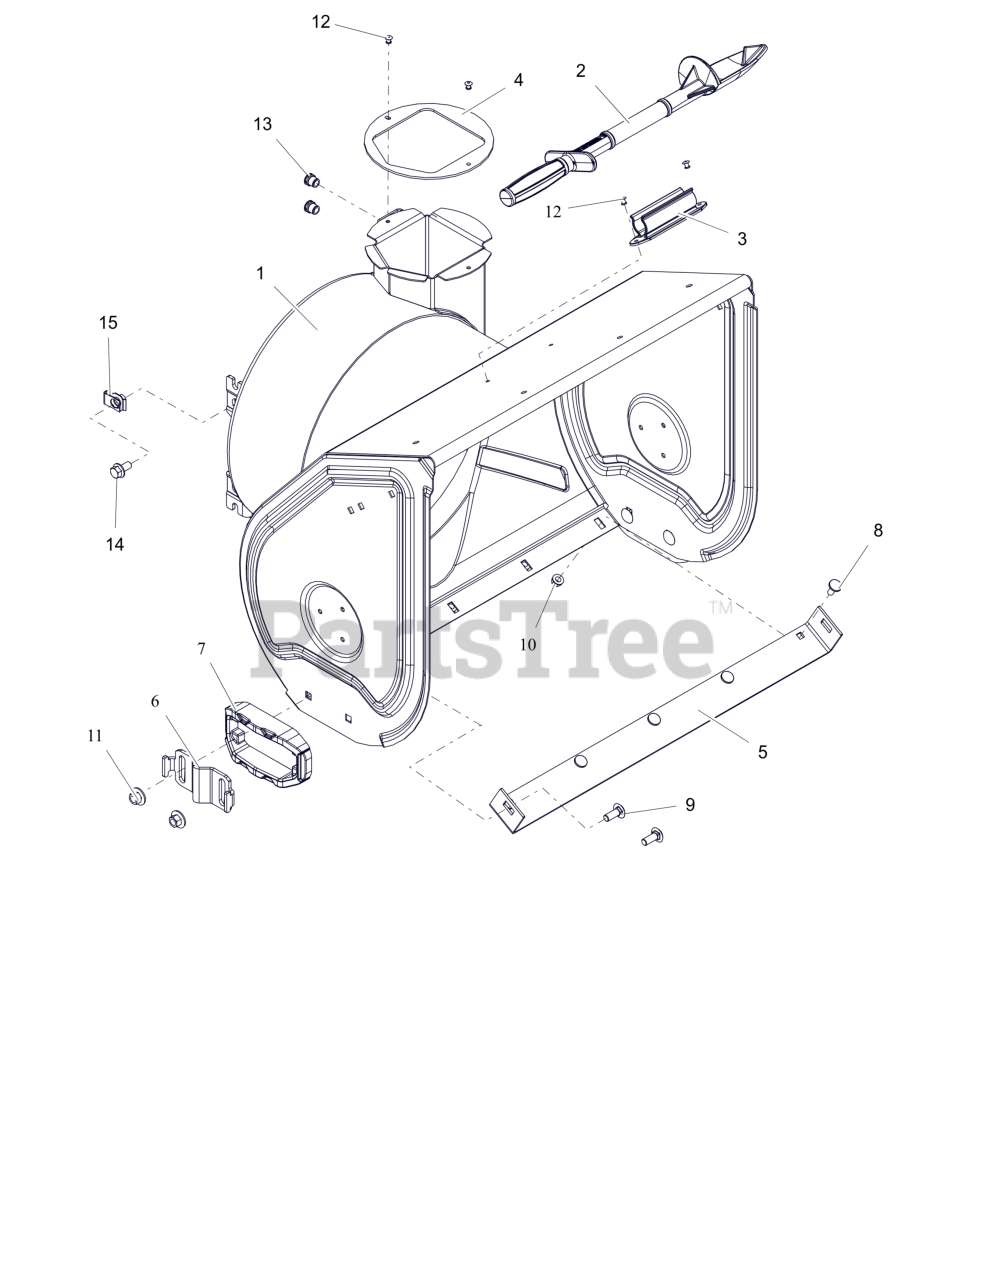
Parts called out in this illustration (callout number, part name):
1	HOUSING, BLOWER W/DECALS 24"
2	DEVICE, SNOW CLEAN OUT
3	MOUNT, SNOW CLEAN OUT
4	BAFFLE, DISCHARGE NECK
5	BLADE, SCRAPER-24"
6	SHOE, SKID - INSERT (BLACK)
7	SHOE, SKID - WEAR
8	BOLT, MODIFIED HEAD CARRIAGE
9	BLT,RHSSN .38-16X1.00 G5 ZCC
10	NUT-LK-TOP-FLG .312-18 GF ZCC
11	NUT- CON-LN .375-16 ZC120
12	RVT, POP .1875 ZCC
13	NUT,THD,INSERT .38-16 ZC120
15	NUT-RTNR .375-16X.37
